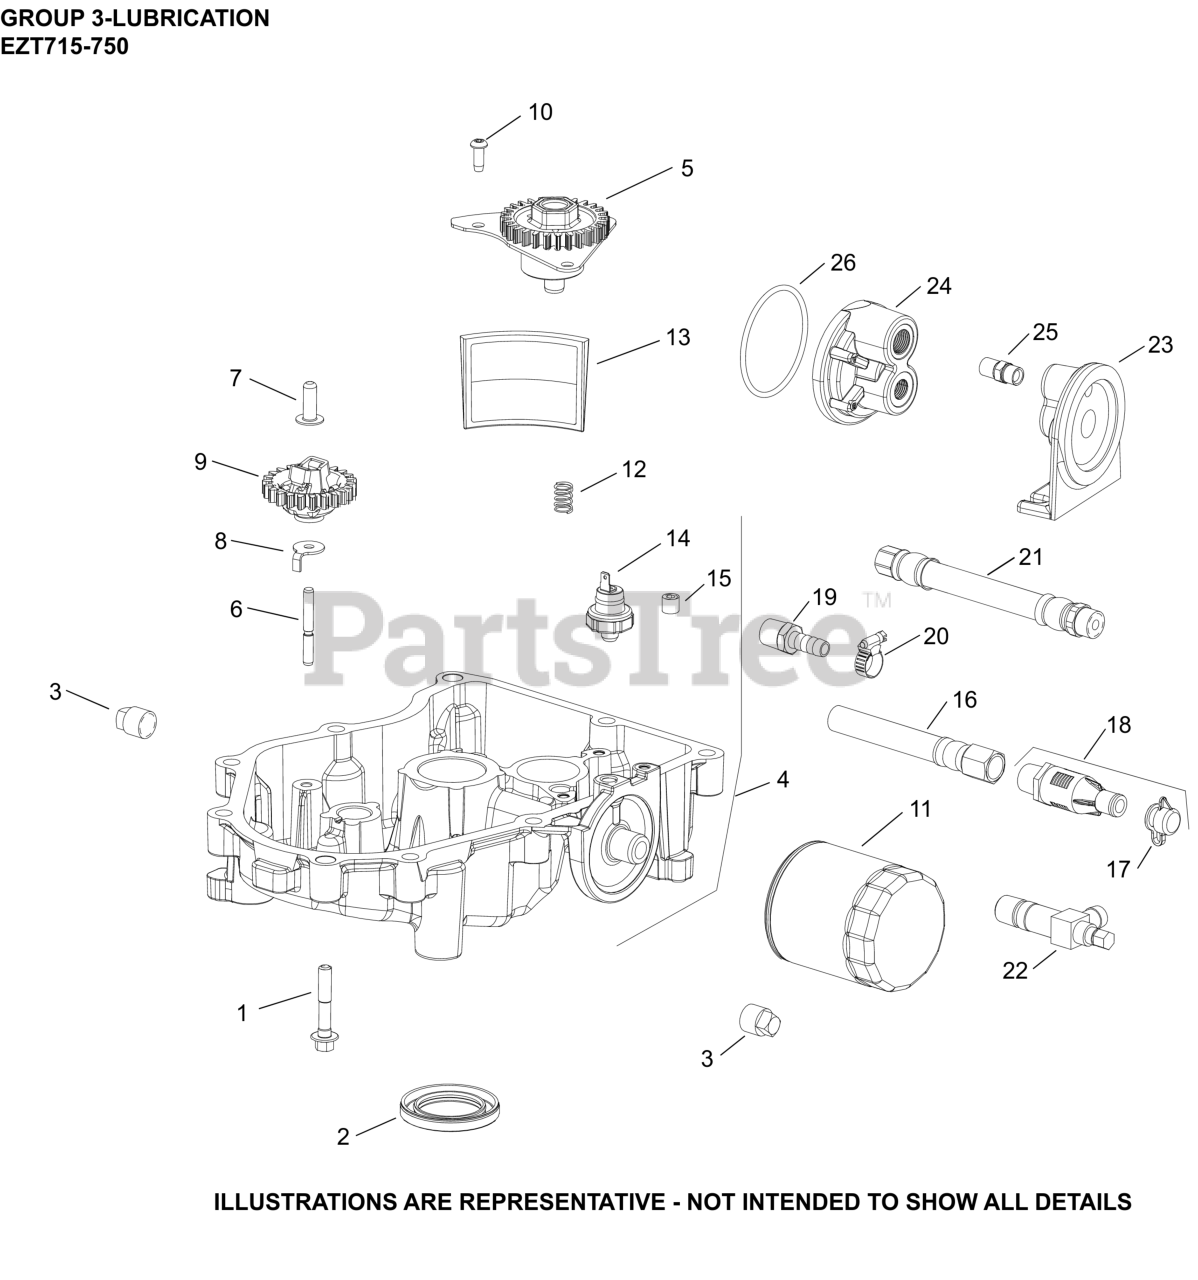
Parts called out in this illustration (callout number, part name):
1	SCREW, FLG M8X1.25X45
3	PLUG, SQ HD PIPE 3/8"
4	OIL PAN ASM (SLEEVE BEARING) (SERVICE)
7	PIN, GOVERNOR REGULATING
8	TAB, LOCKING
9	KIT, GOVERNOR GEAR
10	SCREW, BUTTON HEAD
11	OIL FILTER
12	SPRING, COMPRESSION
13	SCREEN, OIL
15	PLUG, CTSK PIPE 1/8"
NI	SHAFT, GOVERNOR GEAR
NI	PRESSURE RELIEF BALL
